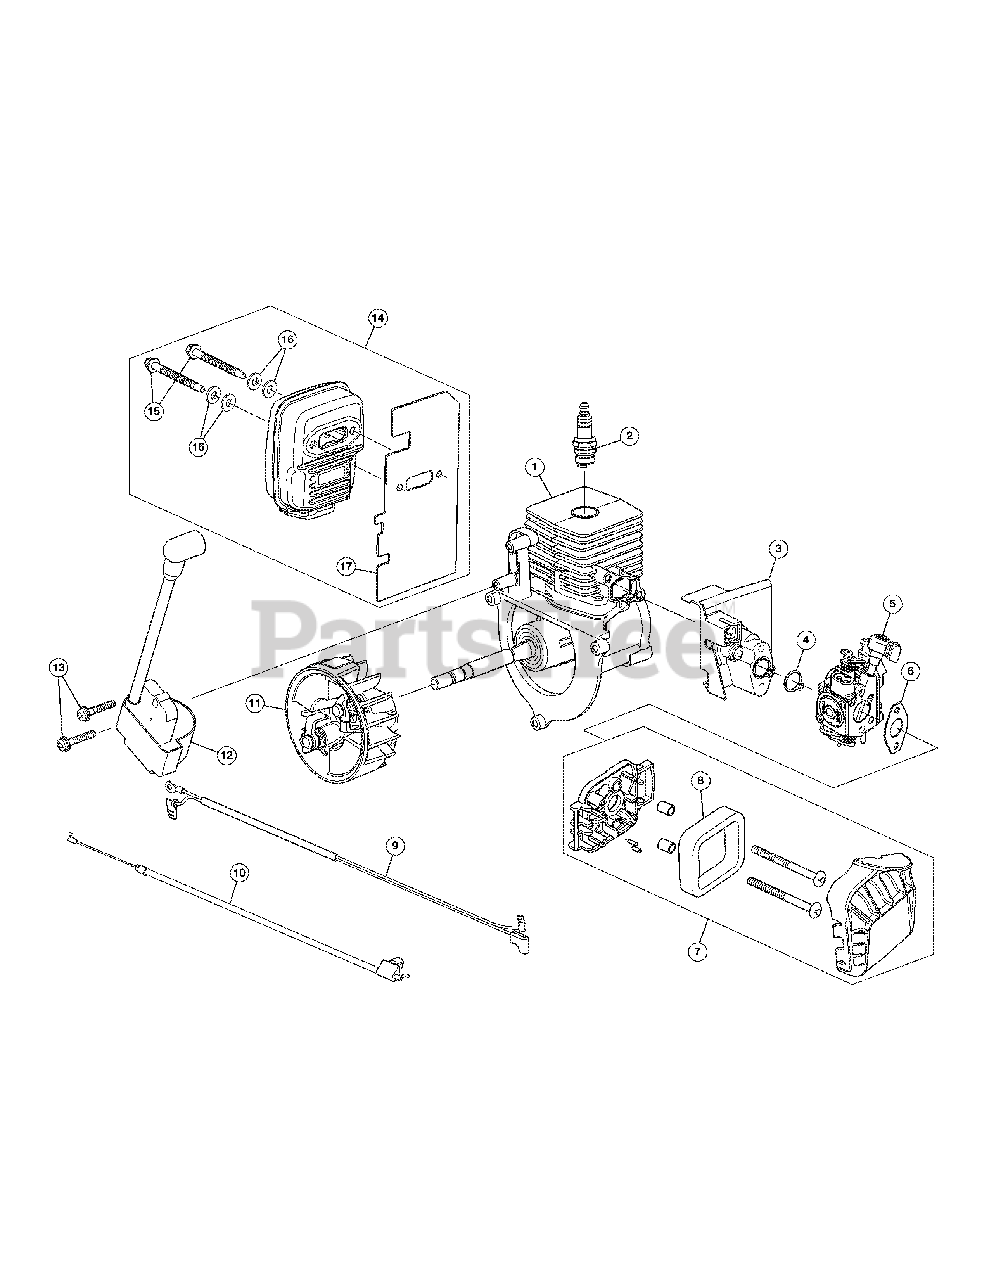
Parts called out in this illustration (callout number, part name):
1	Shortblock Assembly
2	Spark Plug
3	Insulator Assembly
4	O-Ring
5	Carburetor
6	Carburetor Gasket
7	Air Cleaner Assembly
8	Air Cleaner Filter
9	Lead Wire
10	Throttle Cable
11	Flywheel Assembly
12	Module Assembly
14	Muffler Assembly (Incl. 15, 16 and 17)
15	Muffler Screws
16	Washers
17	Muffler Gasket
